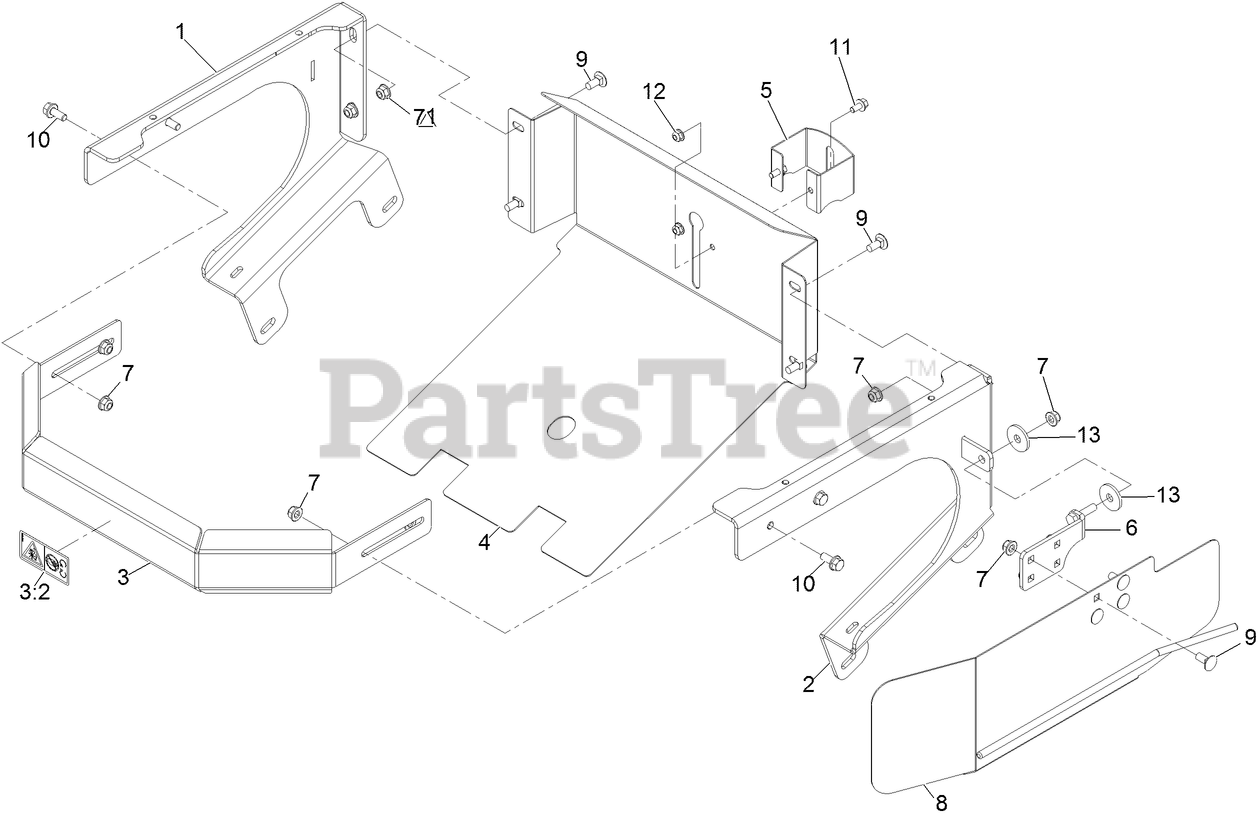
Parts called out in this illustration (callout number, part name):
1	FRAME-HOPPER, RH
2	FRAME-HOPPER, LH
3	BUMPER-FRONT
3:2	Decal-Dismemberment Hazard
4	BACKSHIELD, AE HOPPER
5	BRACKET-CABLE, HOPPER
6	MOUNT-DEFLECTOR
7	Nut-Hex Flange
8	DEFLECTOR-ZPLUG
9	SCREW-CARR
10	SCREW-HHF
11	SCREW-HHF
12	Nut-Hex Flange
13	WASHER
